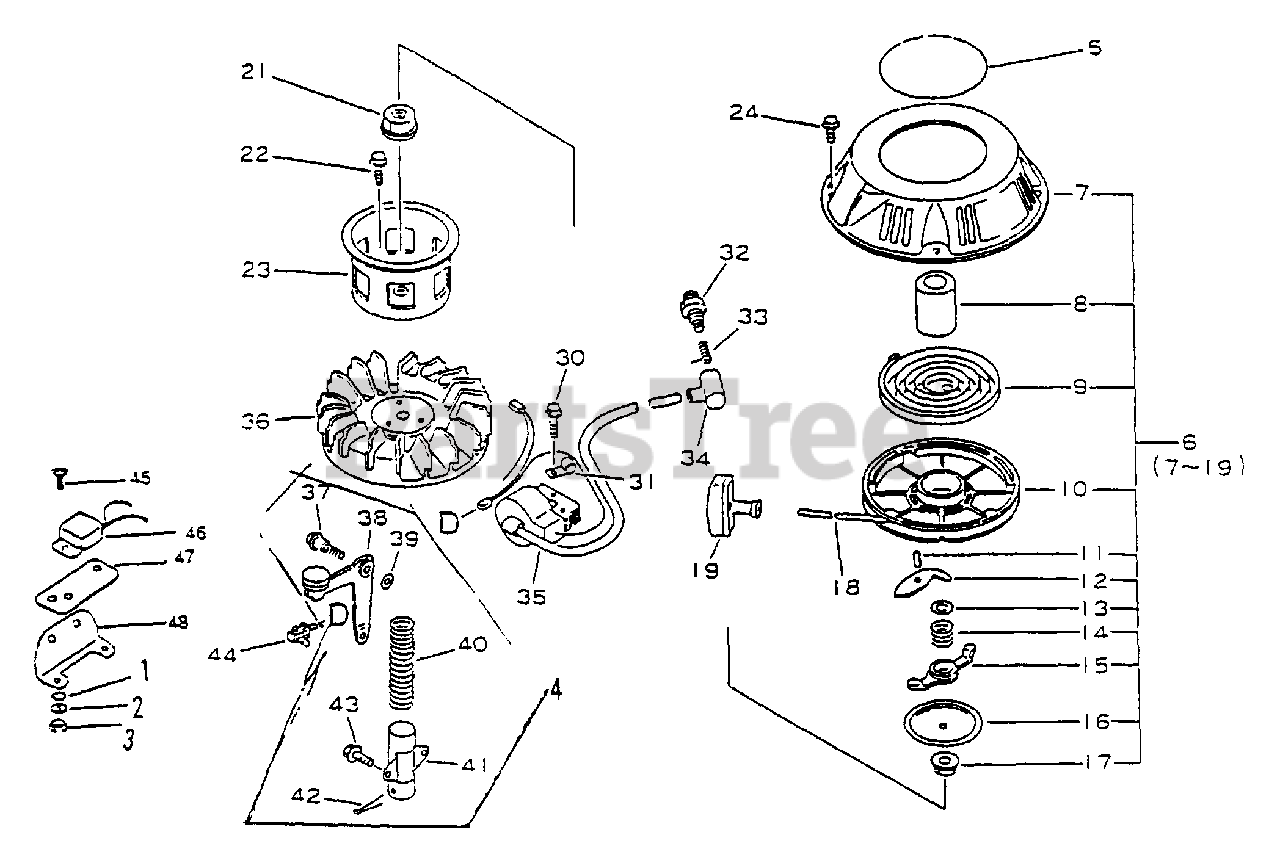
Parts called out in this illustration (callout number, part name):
1	WASHER - 4
2	LOCKWASHER - 4
3	NUT - 4
4	CHAIN BRAKE ASSY
5	LABEL - ECHO
6	STARTER ASSY
7	CASE, STARTER
8	SPACER
9	SPRING, REWIND
10	REEL, ROPE
11	PIN
12	PAWL, STARTER
13	WASHER
14	SPRING
15	GUIDE, PAWL
16	PLATE, FRICTION
17	NUT - 6 -- FLANGE
18	ROPE, STARTER
19	GRIP, STARTER
20	CAP
22	BOLT - 6X10
23	CATCHER, PAWL
24	SCREW - 6X10
30	BOLT - 6X25
31	CLIP
32	SPARK PLUG -- BPM-6A
33	TERMINAL, SPARK PLUG CAP
34	CAP, SPARK PLUG
35	COIL, IGNITION
36	FLYWHEEL
37	SHAFT, BRAKE ARM
38	BRAKE ARM ASSY
39	WASHER - 6
40	SPRING
41	HOLDER, SPRING
42	PIN, SPLIT - 3X30
43	BOLT - 6X10
44	SWITCH, IGNITION
45	SCREW - 4X12
46	COIL, IGNITION
47	PLATE
48	BRACKET, IGNITION COIL
